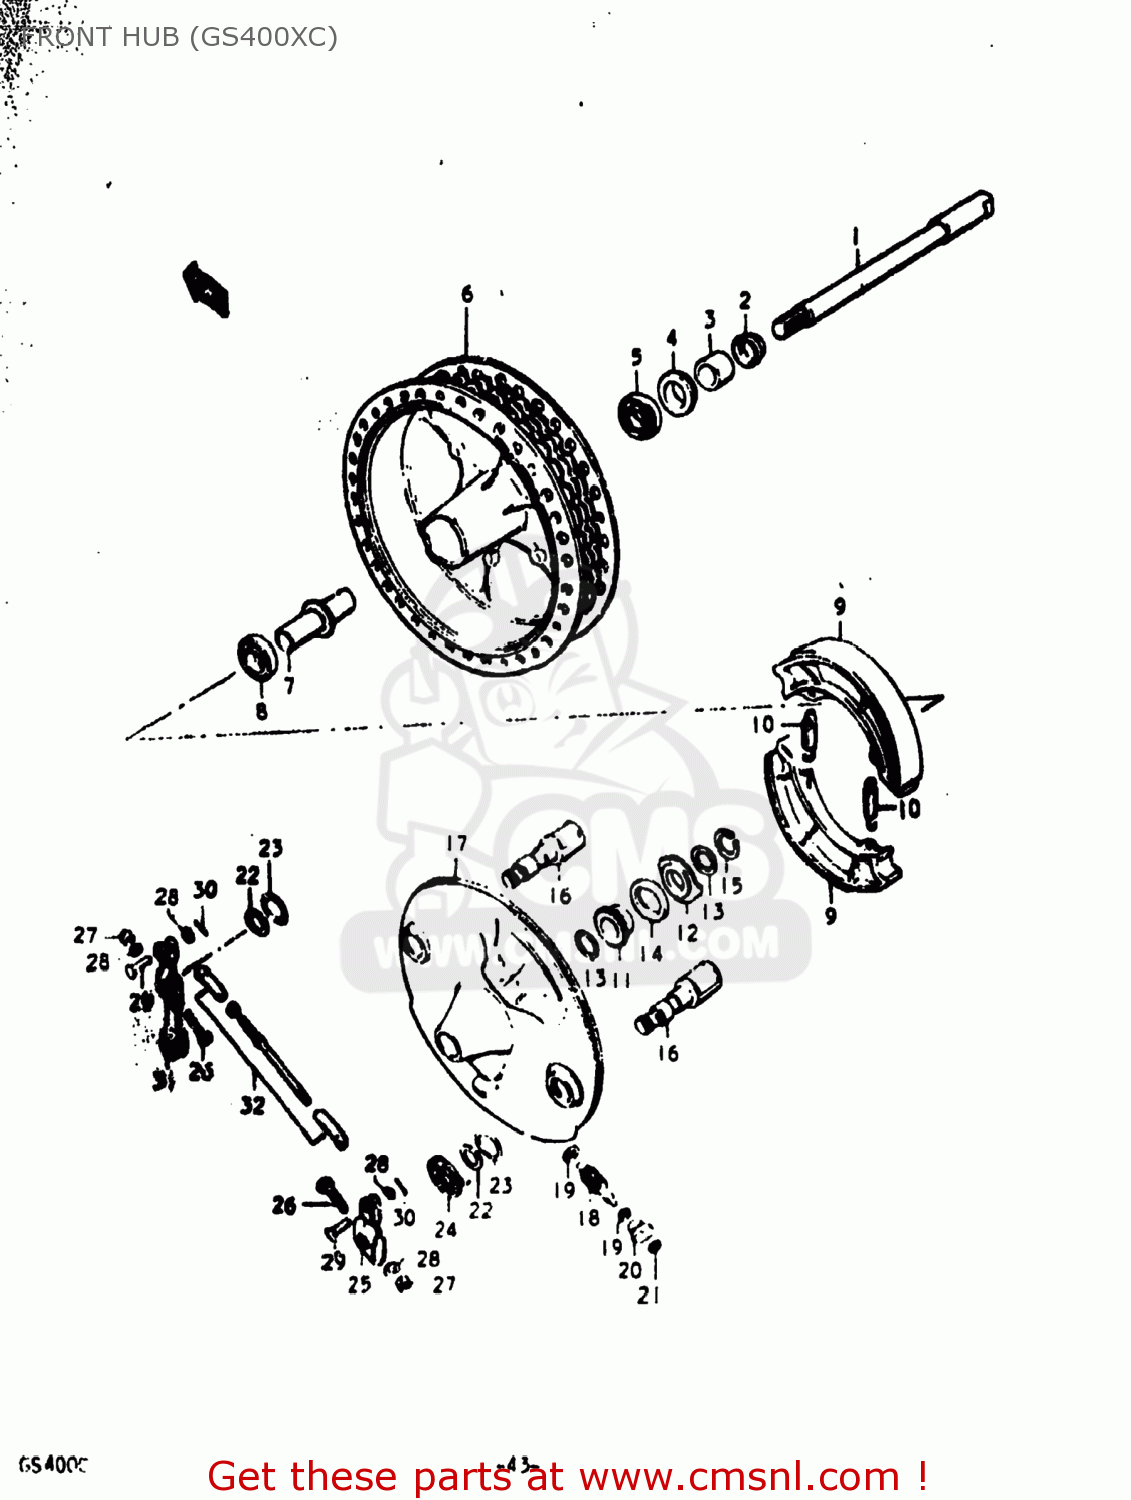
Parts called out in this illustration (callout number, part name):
1	AXLE,FRONT
2	DUST SEAL,FRONT HUB DRUM
3	SPACER
4	OIL SEAL
5	BEARING
6	HUB,FRONT
7	SPACER,FRONT HUB BEARING
8	BEARING
9	SHOE,BRAKE (MCA)
10	SPRING,BRAKE SHOE
11	GEAR,SPEEDOMETER
12	DRIVER,SPEEDOMETER GEAR
13	WASHER(22.5X27X1)
14	OIL SEAL
15	CIRCLIP
16	CAM,FRONT BRAKE
17	PANEL,FRONT HUB
18	PINION,SPEEDOMETER
19	WASHER (5.1X9X0.4)
20	BUSHING,SPEEDOMETER PINION
21	SEAL,OIL(6X10X3)
22	WASHER (15X24X1.6)
23	O-RING,BOSS
24	SPRING
25	LEVER,FRONT BRAKE CAM
26	BOLT
27	NUT
28	WASHER
29	PIN
30	PIN 12X10
31	LEVER,FRONT BRAKE CAM
32	ROD ASSEMBLY,BRAKE CAM LEVER
